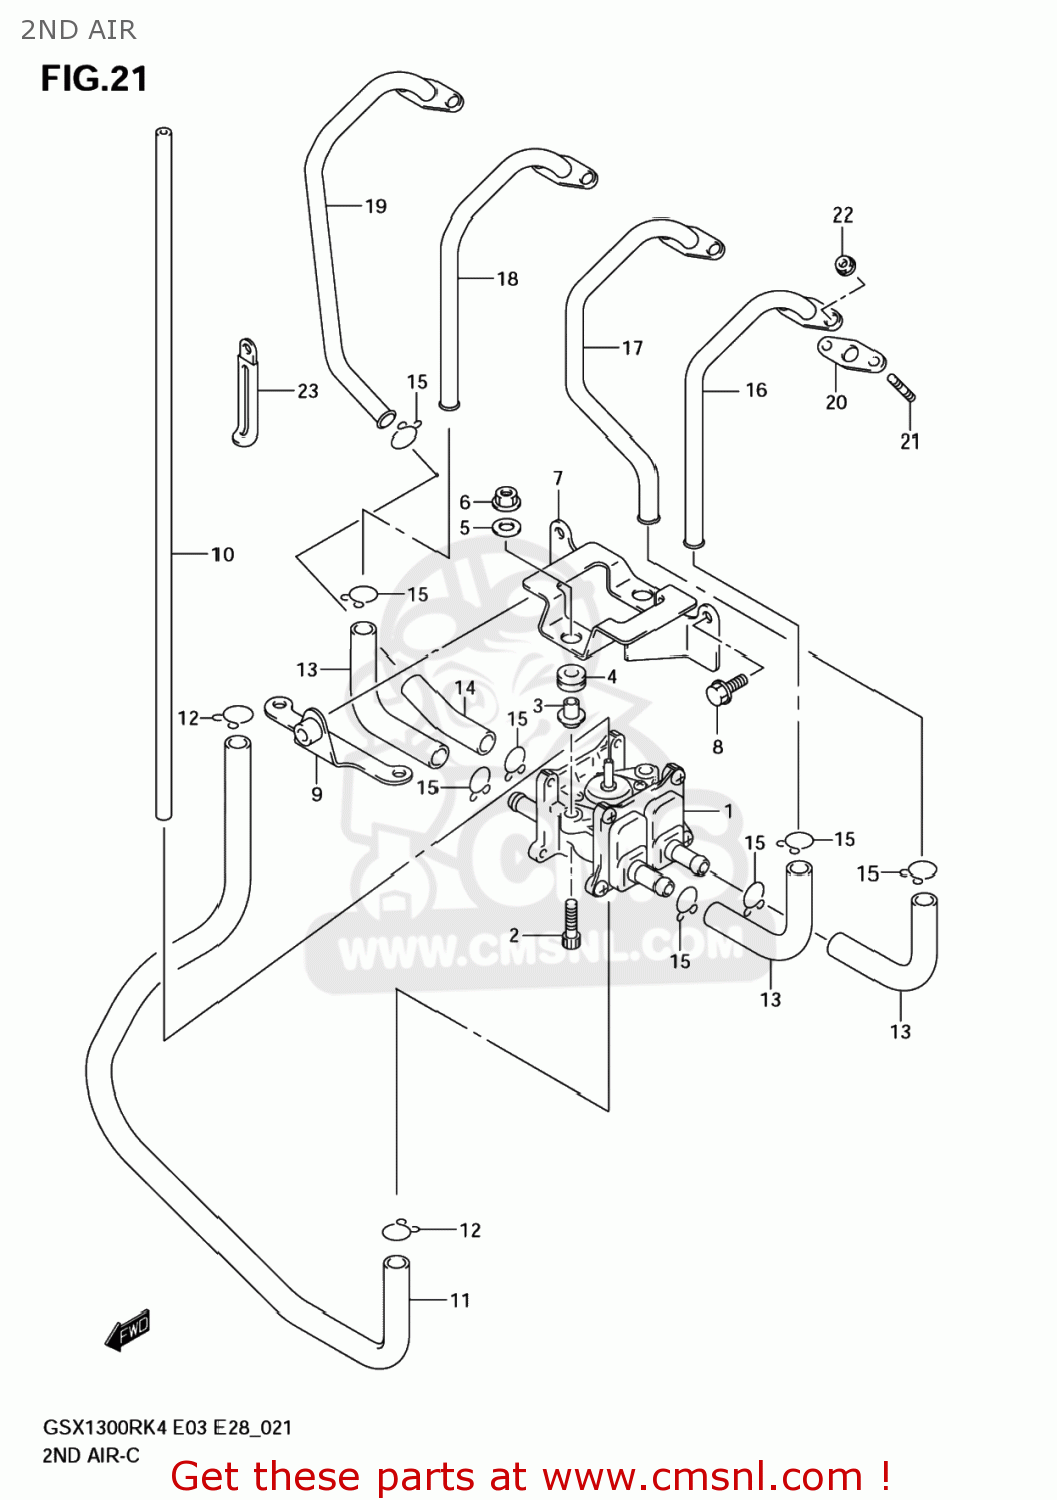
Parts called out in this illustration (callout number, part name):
1	VALVE ASSY,2ND AIR
2	BOLT
3	SPACER,2ND AIR VALVE SPRT
4	CUSHION
5	WASHER(6.5X20X1.6)
6	NUT
7	BRACKET,2ND AIR VALVE
8	BOLT(6X12)
9	BRACKET,2ND AIR VALVE BRKT
10	HOSE(3.5X7.5X2000)
11	HOSE,2ND AIR CLEANER
12	CLIP
13	HOSE,2ND AIR VALVE FR
14	HOSE,2ND AIR VALVE,R
15	CLIP
16	PIPE,2ND AIR NO.1,2
17	PIPE,2ND AIR NO.2
18	PIPE,2ND AIR NO.3,4
19	PIPE,2ND AIR NO.4
20	GASKET,2ND AIR PIPE (NAS)
21	STUD BOLT
22	NUT
23	CLAMP(L:45)
